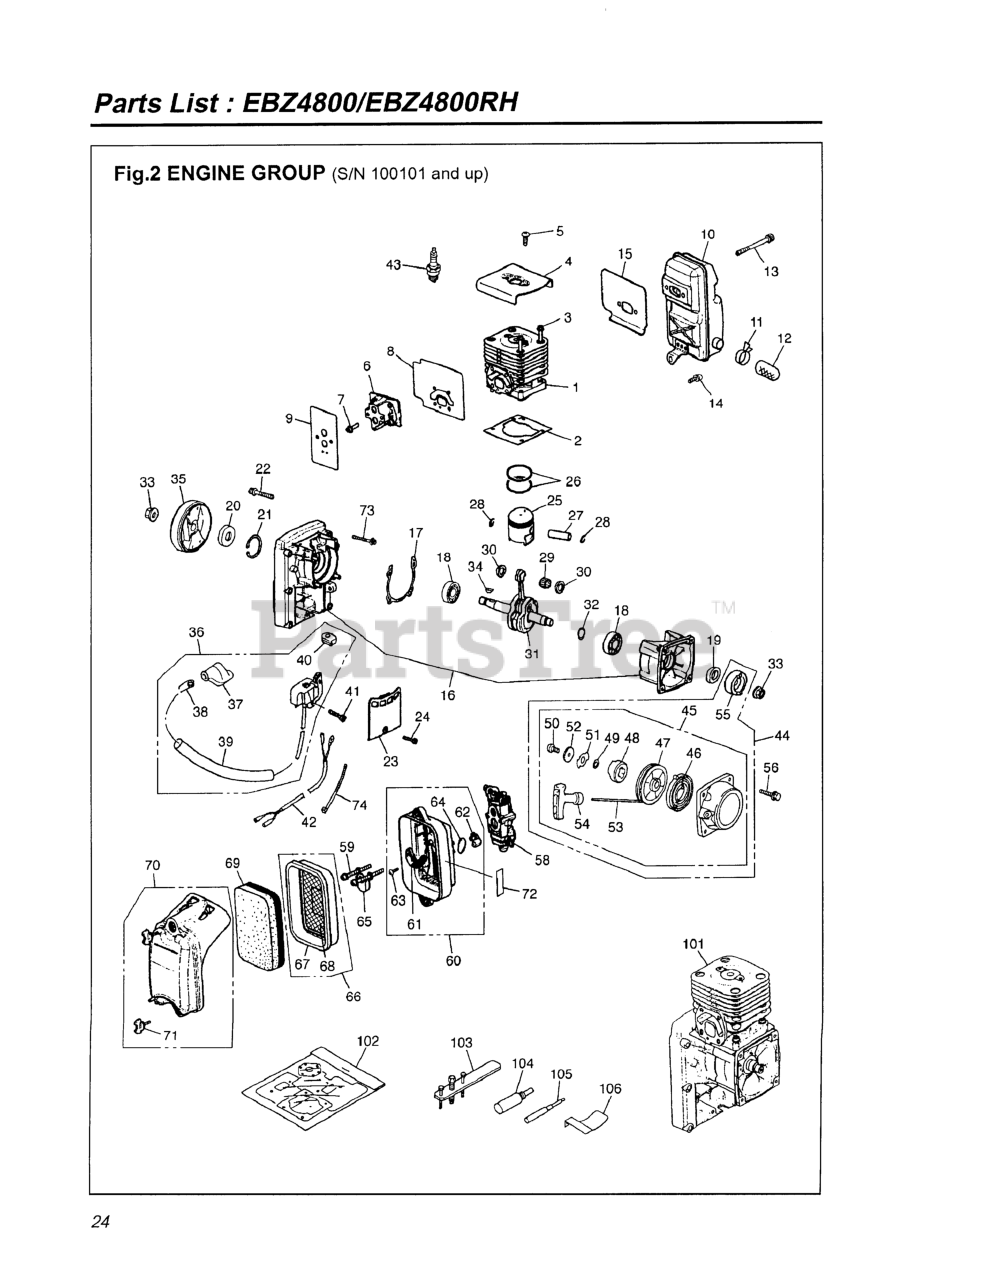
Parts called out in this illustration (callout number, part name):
1	CYLINDER
2	GASKET, BASE
3	BOLT
4	PLATE, CYLINDER
5	SCREW TORX
6	INSULATOR
7	BOLT (USE 848-815-2000)
8	848-GC0-14B1
9	GASKET, CARBURETOR
10	MUFFLER
11	ARRESTER
13	BOLT
14	BOLT
15	GASKET, MUFFLER
16	CRANKCASE COMP
17	GASKET, CASE
18	BEARING (REPLACES 2810-21240)
19	SEAL, OIL 15 X 25 X 7
20	SEAL (REPLACES 1400-21220)
21	RING, SNAP, M35 X 1.5
22	BOLT
23	COVER
24	BOLT TORX
25	PISTON
26	RING, PISTON (REPLACES -41210)
27	PIN, PISTON
28	RING, SNAP
29	BEARING
30	WASHER (RPLS 1491-41510)
31	CRANKSHAFT COMP
32	SHIM (REPLACES 848-870-G000)
33	NUT, M10
34	KEY
35	ROTOR
36	COIL ASSY.
37	CAP
38	SPRING
39	TUBE
40	GROMMET
41	BOLT TORX
42	CORD-C
43	SPARK PLUG (CMR7H)
44	STARTER ASSY (REPLACES -75000)
45	RECOIL ASSY (RPLS -75100)
46	SPRING (RPLS -75220)
48	DOG
49	WASHER
50	SCREW
51	RETAINER (RPLS 1861-75161)
52	WASHER
53	ROPE
54	KNOB
55	PULLEY (RPLS -75210)
56	SCREW TORX
58	CARBURETOR (WYA 24A)
59	BOLT
60	BODY-A
61	PLATE,CHOKE
62	LEVER
64	RING,O
65	PLATE
66	PACKING-C
67	PACKING
69	ELEMENT
70	COVER-A
71	KNOB
72	LABLE,CHOKE
73	BOLT
101	SHORT BLOCK
102	GASKET KIT
103	PULLER ASSY
104	STOPPER (TOOL)
105	PULLER, PISTON PIN
